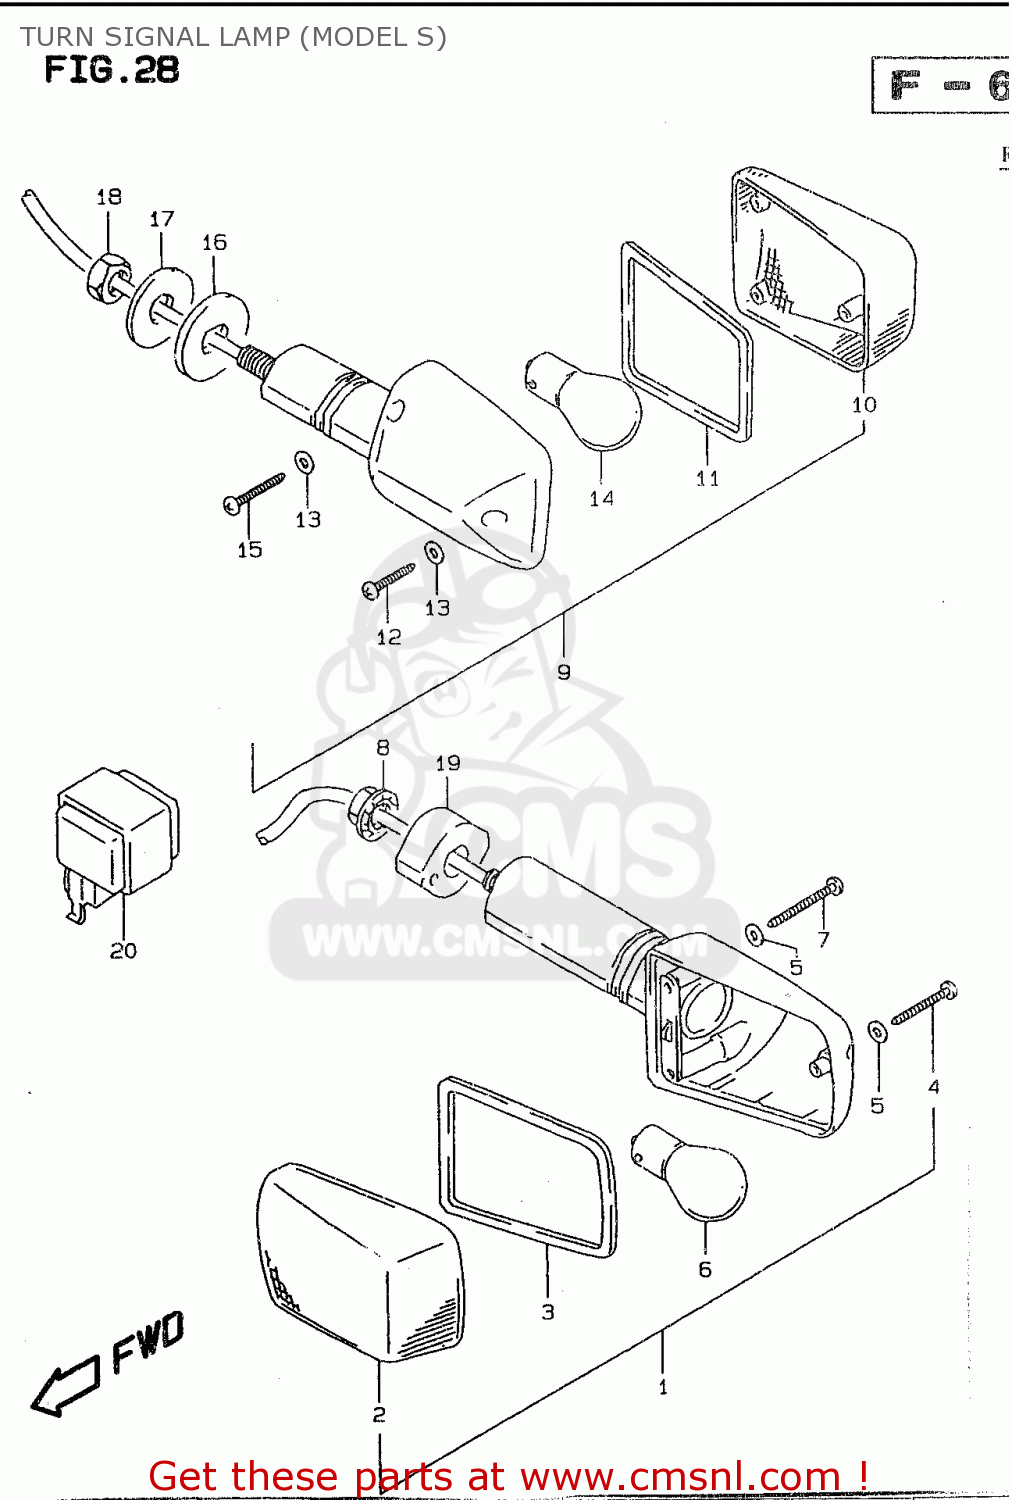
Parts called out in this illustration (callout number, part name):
1	LAMP ASSY,FR TURN SIGNAL
2	LENS
3	GASKET (NAS)
4	SCREW
5	GASKET (NAS)
6	BULB(12V21W)
7	SCREW(3X30)
8	NUT
9	LAMP ASSY,RR TURNSIGNAL
10	LENS
11	GASKET (NAS)
12	SCREW
13	GASKET (NAS)
14	BULB(12V21W)
15	SCREW(3X30)
16	SPACER,RR TURNSIGNAL
17	WASHER(10.5X30X2.3)
18	NUT
19	SPACER,FR TURNSIGNAL LAMP
20	RELAY ASSY,TURNSIGNAL LAMP
